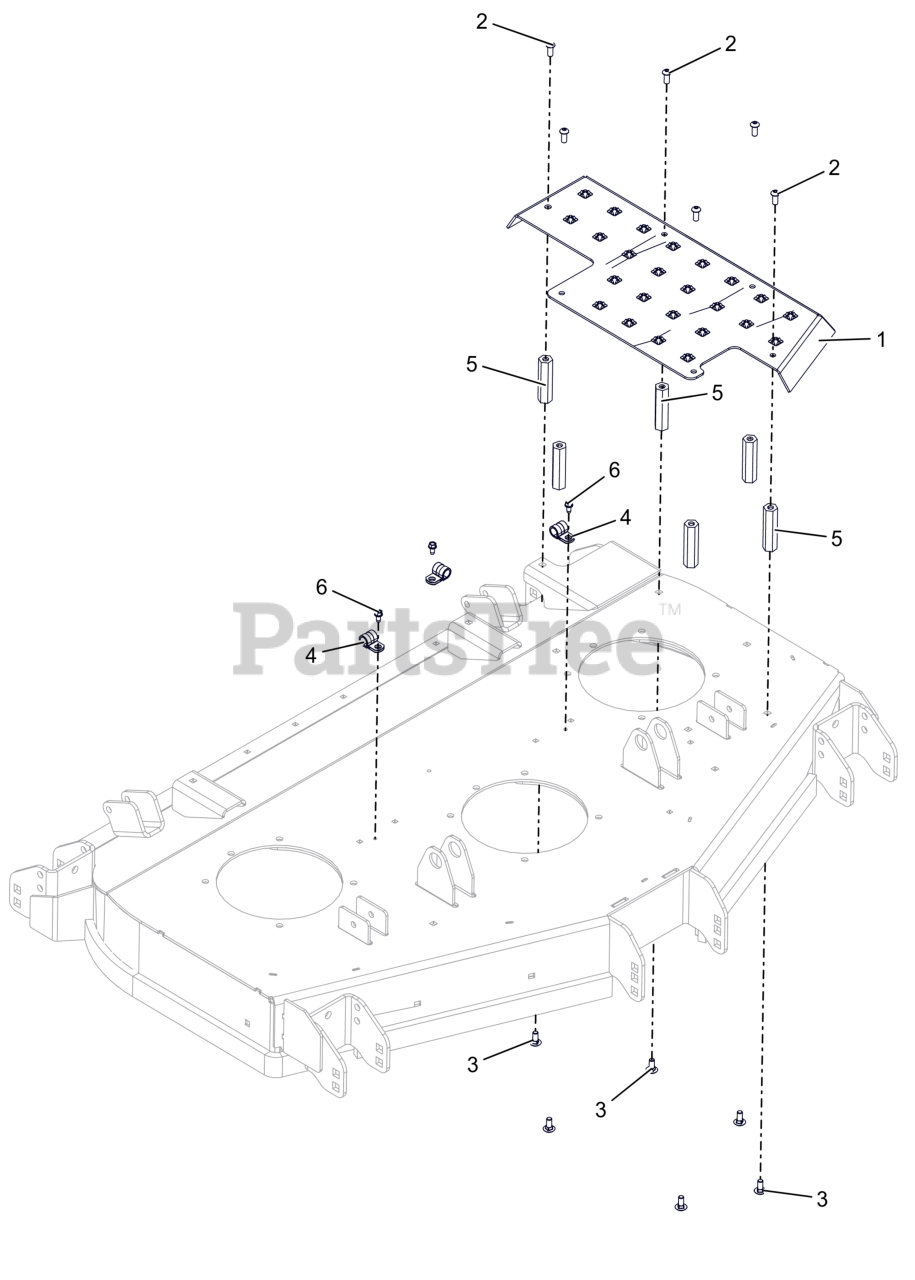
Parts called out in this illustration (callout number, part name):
1	PLATFORM, WLDMT 48 RD DECK STEP (ORANGE)
2	SCR-SKH .31-18X.75 BTNHD YWZC
3	BLT, RHSN .31-18X.75 G5 ZCC LT
4	CLAMP, CUSHIONED STEEL
5	NUT, COUPLING .31-18 X 3.00
6	SCR-TAP .25-20X.50 HWH ZCC
